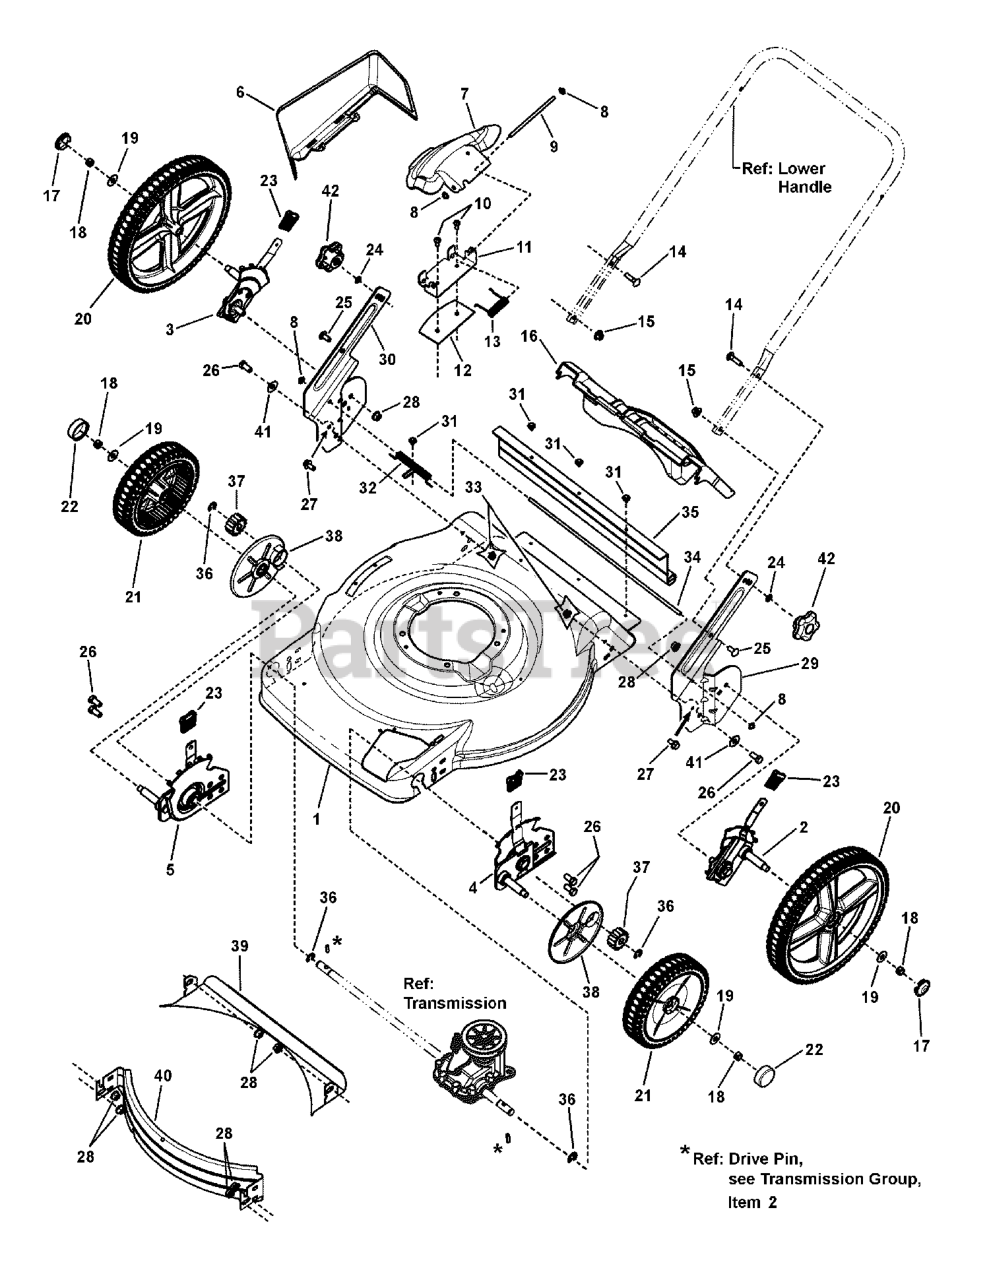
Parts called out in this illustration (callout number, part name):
1	DECK, 22" Walk, 3-N-1
2	ASSEMBLY, Height-Of-Cut, 22", 7 Position, Left Rear
3	ASSEMBLY, Height-Of-Cut, 22", 7 Position, Right Rear
4	ASSEMBLY, Height-Of-Cut, 22", Propelled, 7 Position, Left Front
5	ASSEMBLY, Height-Of-Cut, 22", Propelled, 7 Position, Right Front
6	SIDE CHUTE, Plastic, Black
7	COVER, Mulch, Plastic, Black
8	PUSHNUT, 1/4"
9	ROD, Pivot, Chute
10	SCREW, Torx, 1/4-20 x 11/16"
11	BRACKET, Chute
12	PLATE, Mulch
13	SPRING, Torsion, Chute
14	BOLT, 5/16-18 x 1" Round Head Square Neck Carriage, GR 5
15	NUT, Hex, 5/16-18
16	DOOR, Rear Discharge
17	HUBCAP, 12" Wheel
18	NUT, 3/8-16 Hex Center Lock
19	WASHER, 1" O.D. x .387 I.D. Flat, 1
20	ASSY, Wheel, 12" x 2" Idle, NB, Murray Tread, Pewter
21	WHEEL, 8 x 2, Drive
23	GRIP, Height Latch, Black
24	WASHER, Internal Tooth Lock, 5/16"
25	BOLT, Carriage, 5/16-18 x 3/4"
26	SCREW, 3/8-16 x 3/4" Hex Head Cap
27	BOLT, Hex Flange, 5/16-18 x 5/8
28	NUT, 3/8-16 Hex Flange Lock
29	BRACKET, Lower Handle, Left
30	BRACKET, Lower Handle, Right
31	SCREW, Self Tap, SEMS, 10-24 x 1/2
32	SPRING, Torsion, Rear Door
33	NUT, Hex Flange Lock, 5/16-18
34	ROD, Pivot, Rear Door
35	GUARD, Rear 22" Hi-Wheel
36	RETAINING RING
37	GEAR, Pinion
38	SHIELD, Dust
39	BAFFLE, Rear
40	BAFFLE, Front, 22" WBM
41	WASHER, .375 I.D. x .875 x .083 Flat
42	KNOB, Handle
